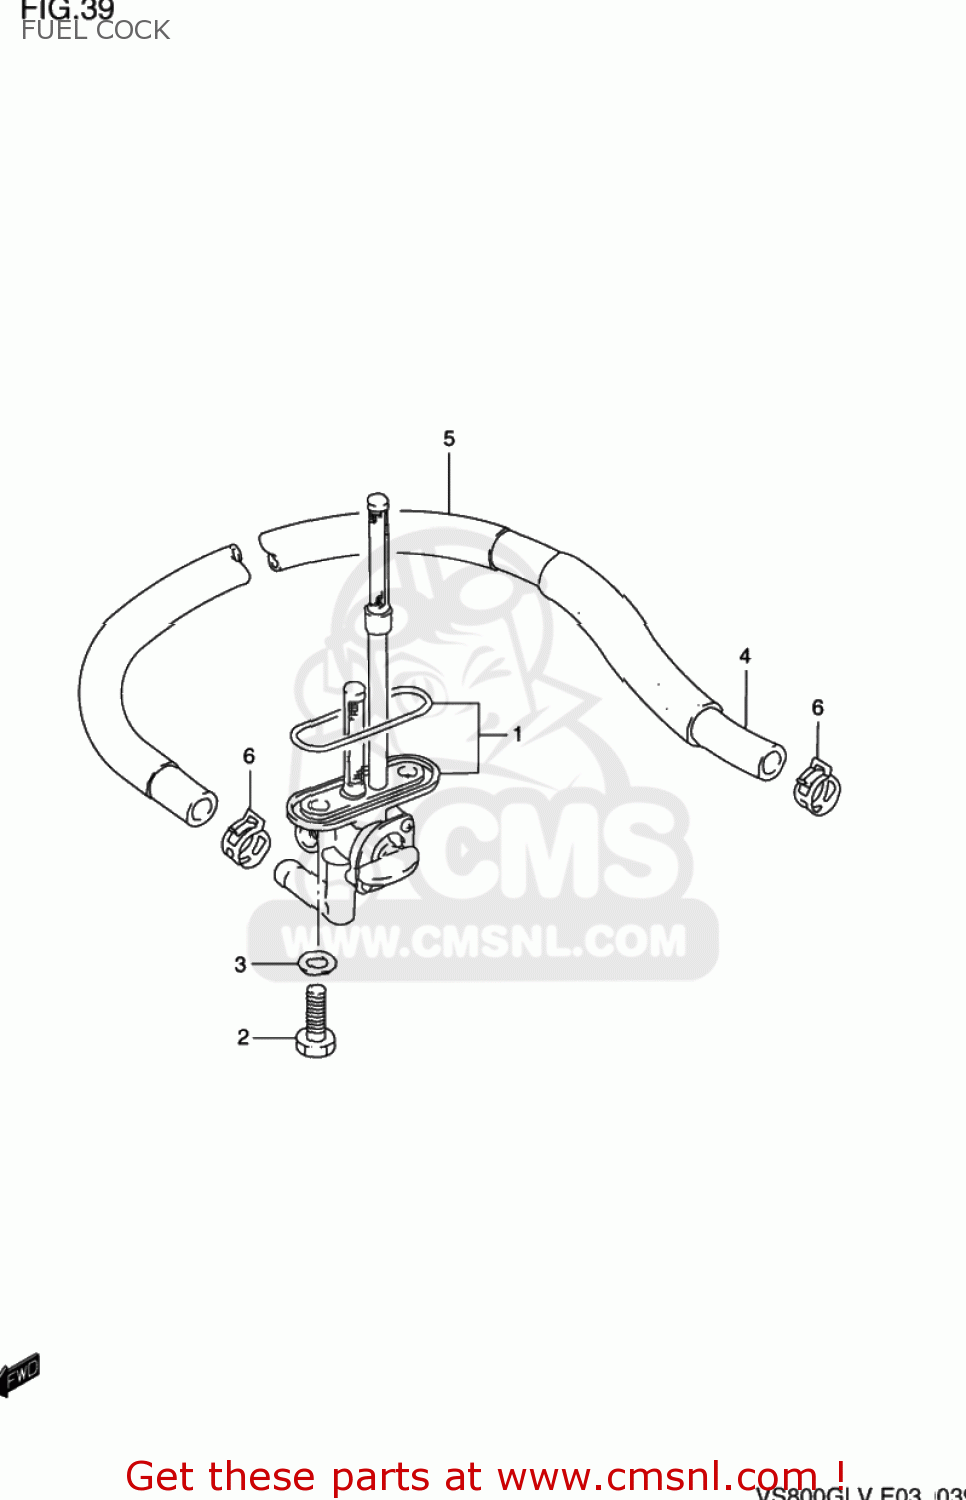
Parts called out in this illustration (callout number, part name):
1	COCK ASSY,FUEL
2	BOLT(6X20)
3	GASKET(6.4X11.5X0.8) (NAS)
4	HOSE,FUEL PUMP & COCK
5	TUBE,FUEL HOSE
6	CLIP
